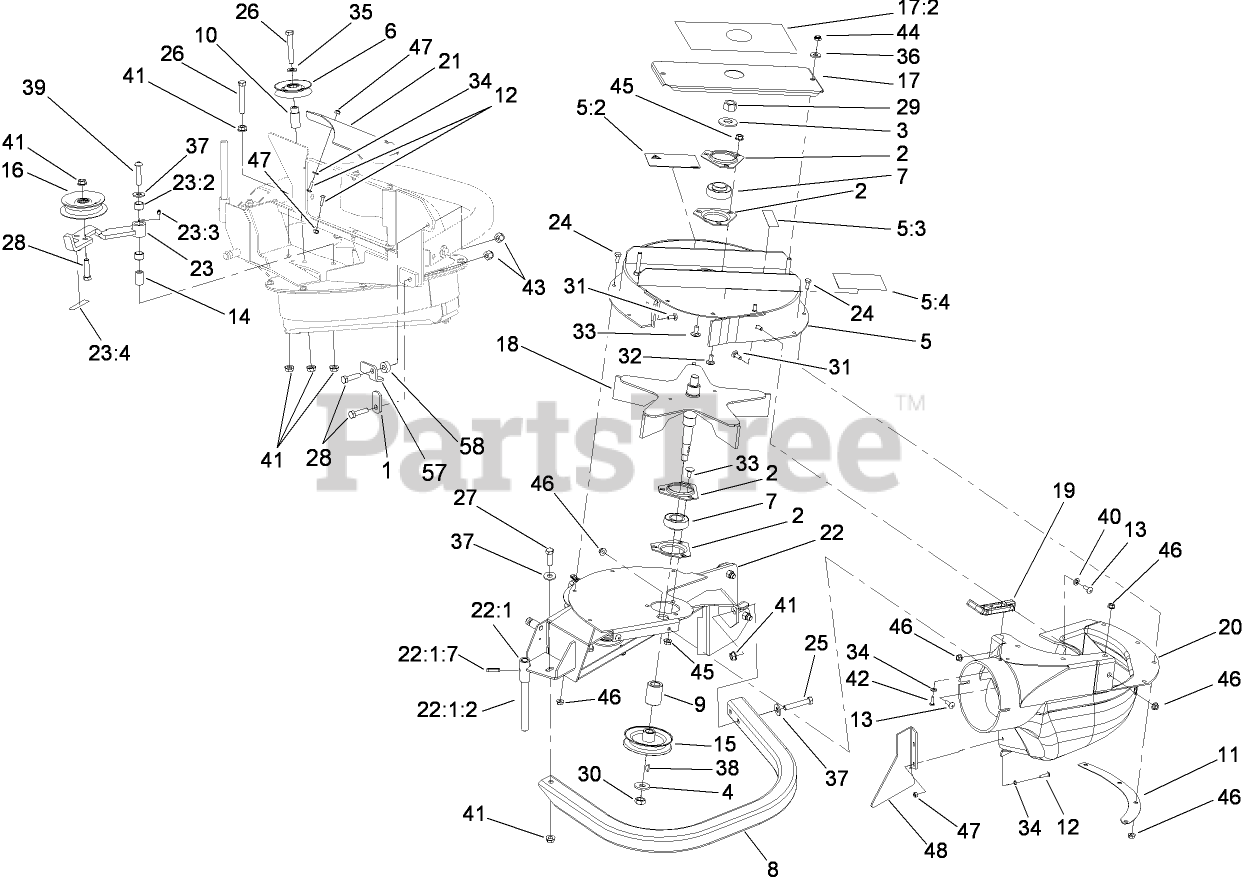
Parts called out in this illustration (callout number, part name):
1	LATCH-CATCHER, GRASS
2	HOUSING-FLANGE
3	WASHER-SPRING
4	WASHER-SPRING
5	UPPER HOUSING ASM
5:2	DECAL-WARNING
5:3	DECAL-COVER, MISSING
6	IDLER-INSIDE
7	BEARING
9	SPACER
11	PLATE-BACKING, BLOWER
12	SCREW-HSBH
13	SCREW-HSBH
14	BUSHING-PIVOT, IDLER
15	PULLEY
16	IDLER-FLAT
17	BEARING COVER ASM
17:2	DECAL-WARNING
18	IMPELLER
19	LATCH-RUBBER
20	CHUTE-BLOWER, SMALL
21	PLATE-BOTTOM
22	BLOWER MOUNT ASM
22:1	MOUNT-BLOWER
22:1:2	SHAFT-CATCHER, GRASS
22:1:7	PIN-ROLL
23	IDLER ARM ASM
23:2	BUSHING
23:3	FITTING-GREASE
23:4	DECAL-WARNING
24	SCREW-HH
25	SCREW-HH
26	SCREW-HH
27	SCREW-HH
28	SCREW-HH
29	NUT-HEX
30	NUT-JAM
31	BOLT-CARR
32	SCREW-CARR
33	SCREW-CARR
34	WASHER-FLAT
35	WASHER-FLAT
36	WASHER-FLAT
37	WASHER-FLAT
38	KEY-WOODRUFF
39	SCREW-HSBH
40	WASHER-FLAT
41	NUT-HHF, WHIZ
42	SCREW-HSBH
43	NUT-LOCK, NI
44	NUT-LOCK, NI
45	NUT-HF
46	NUT-HF
47	NUT-LOCK, NI
48	PLATE-FILLER, REAR
57	LATCH-STOP
58	SPACER
